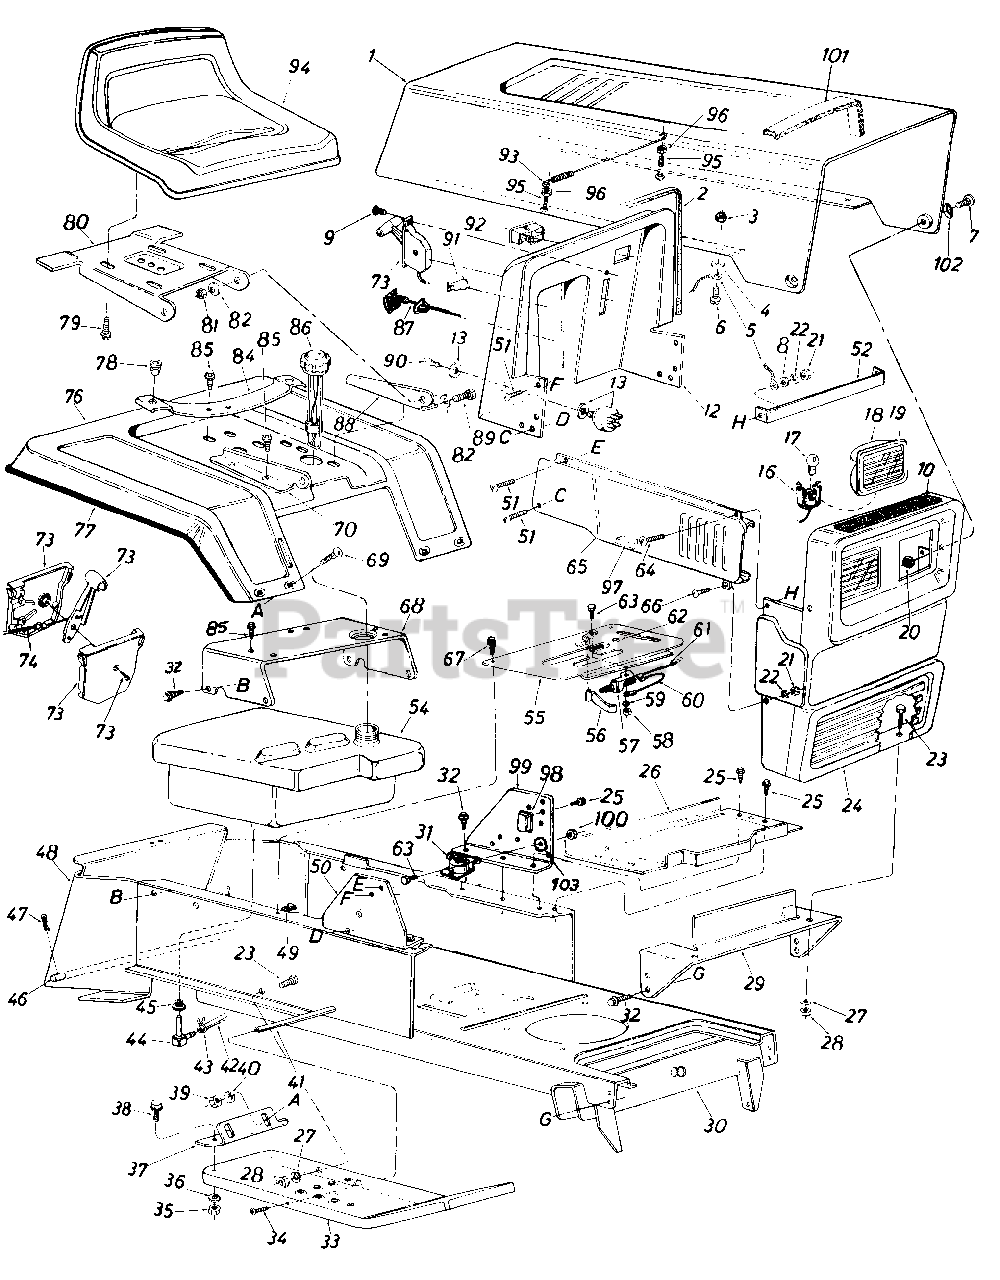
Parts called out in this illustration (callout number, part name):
1	Hood
2	Trim Strip-27" Lg.
3	Fl-Wash. .20" I.D. x .41"
5	Hood Stop
6	Truss Hd. Mach. Scr. #10-24 x.50" Lg.
7	Shld. Bolt .375 Dia. x .125
8	Fl-Wash. 1/4" I.D.
9	Truss Mach. AB-Tap Scr. #10 x .50" Lg.
10	Foam Strip 3/8" x 1" x 14"
12	Dash Ass'y.
13	Ignition Switch
16	Socket
17	Lamp
18	Headlight Housing
19	Lens
20	L-Nut 1/4-28 Thd.
21	Hex Nut 1/4-20 Thd.
22	L-Wash. 1/4" I.D.
23	Hex Bolt 5/16-18 x .75" Lg.*
24	Grille
25	Hex Wash. Hd. Scr. 1/4" x .50" Lg.
26	Battery Plate
27	L-Wash. 5/16" I.D.
28	Hex Nut 5/16-18 Thd.
29	Grille Mounting Bracket
30	Lower Frame Ass'y.
31	Solenoid
32	Hex Thd. Rolling Scr. 5/16-24 x .75" Lg.
33	Running Board-R.H.
34	Truss Mach. Scr. 5/16-18 x .75" Lg.
35	Hex Nut 5/16-18 Thd.
36	Bell-Wash. .34" I.D. x .87" O.D.
39	Hex Nut 1/4-20 Thd.
40	L-Wash. 1/4" I.D.
41	Running Board Rod
42	Fuel Line 40" Lg.
43	Hose Clamp 3/8"
44	90ø Nipple
45	Bushing
46	Hitch Rod
47	Internal Cotterpin
48	Hitch Plate
49	Speed Nut
50	Dash Support Brkt.-R.H.
51	Hex Wash. Hd. Tap Scr. 1/4 x.75" Lg.
52	Tie Strap
54	Fuel Tank
55	Transmission Cover Ass'y.
56	Switch Actuator Spring Lever
57	Safety Switch
58	Hex Nut 1/4-20 Thd.
59	L-Wash. 1/4" I.D.
60	Electric Wire
61	Reverse Lockout Wire Harness
62	Snap Bushing
63	Hex Bolt 1/4-20 x .50" Lg.
64	Truss Hd. Scr. 1/4-20 x .75" Lg.
65	Side Panel-R.H.
66	Truss Mach. Scr. 1/4-20 x .50" Lg.
67	Truss Mach. "B" Tap Scr. #10 x .50" Lg.
68	Seat Mounting Channel
69	Carriage Bolt 1/4-20 x .50"
70	Seat Bracket-R.H.
73	Throttle Control Box Ass'y.
74	Throttle Control Wire
78	Grommet
79	Hex Wash. Hd. AB-Tap Scr. 318 x .75" Lg .
80	Seat Pivot Bracket
81	Hex Cent. L-Nut 5/16-18 Thd.
82	Belleville Wash. .34" I.D. x .88" O.D.
84	Seat Spring
85	Hex Wash. Hd. Self-Tap Scr. 5/16-18 x .50" Lg.
86	Gas Cap w/Gauge
87	Choke Control Comp.
88	Seat Bracket-L.H.
89	Hex Bolt 5/16-18 x .75" Lg.
90	Ignition Key
91	Light Switch
92	Ammeter
93	Hood Spring
94	Seat Ass'y.
95	Hex Bolt #10-24 x 1.0" Lg.
97	Rubber Strip 1/2" Sq. x 2-1/2 " Lg.
98	Circuit Breaker
99	Dash Support Brkt.-L.H.
100	Hex Sems Nut 1/4-20 Thd.
101	PVC Foam Strip
102	Washer .34" I.D. x .62" O.D.
103	External L-Wash. I.D.
